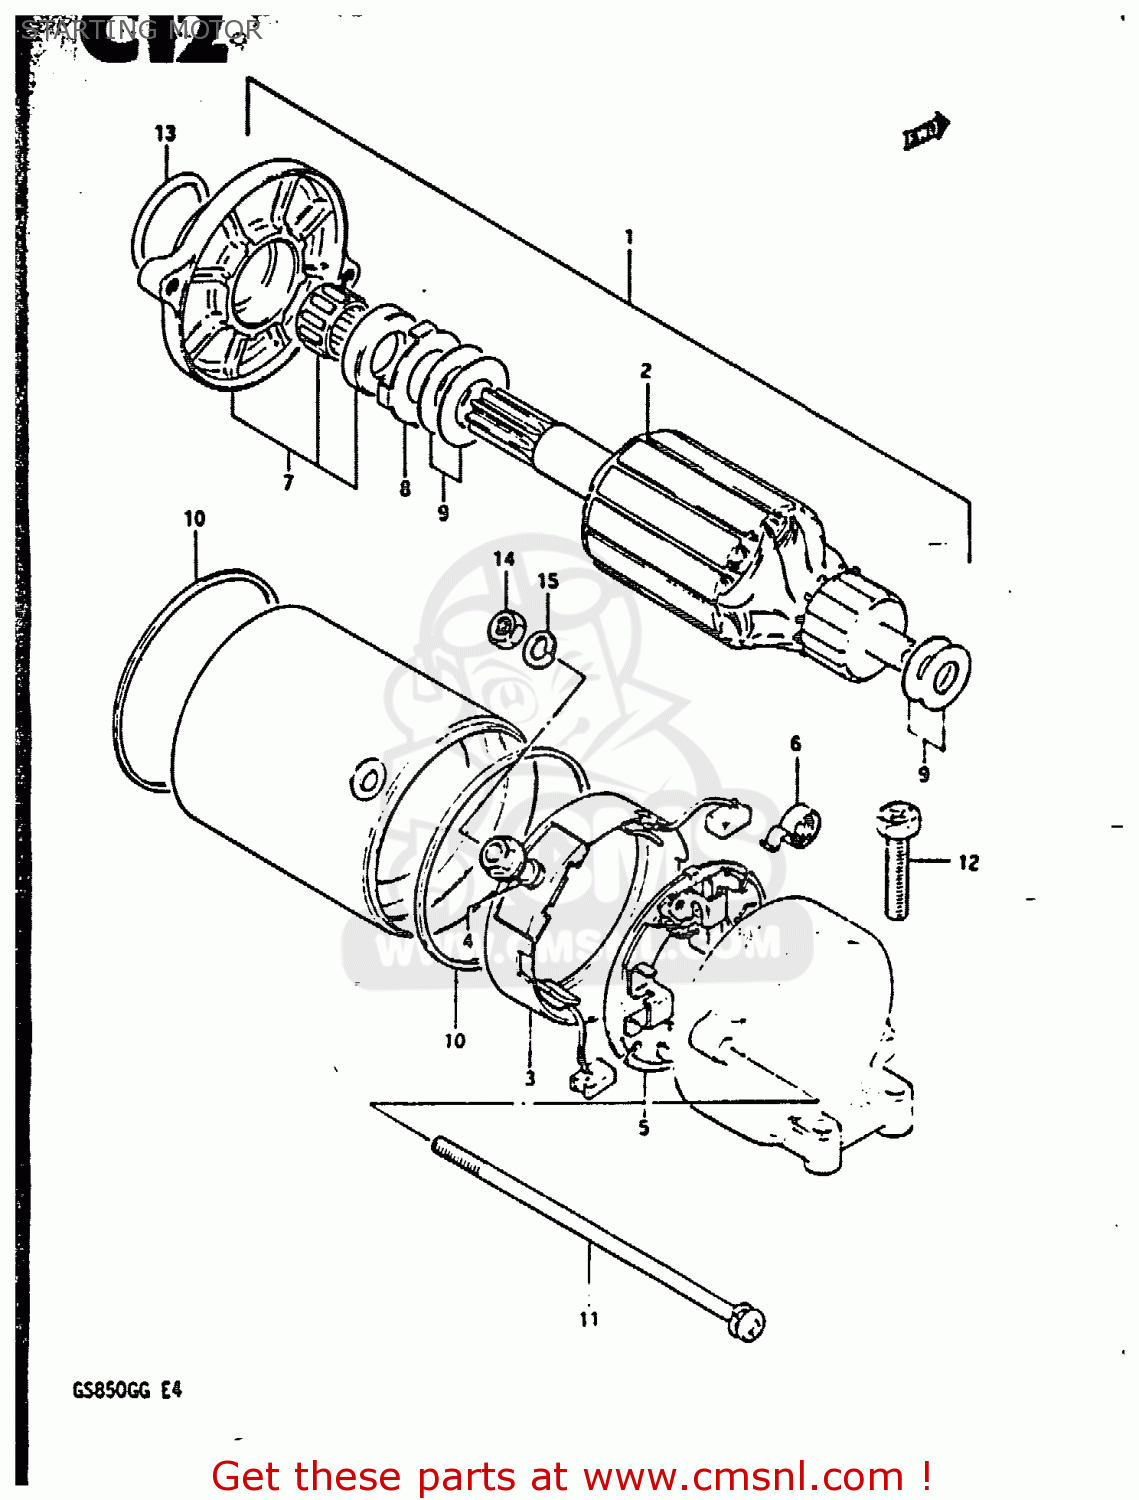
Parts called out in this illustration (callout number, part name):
1	MOTOR ASSEMBLY,STARTING
2	ARMATURE
3	BRUSH TERMINAL SET (+)
4	O RING
5	HOLDER,BRUSH
6	SPRING,BRUSH
7	HOUSING SET,STARTING MOTOR
8	SHIM SET
9	SHIM SET
10	SEAL,RING
11	BOLT,STARTING MOTOR HOUSING
12	SCREW (6X25)
13	O RING(D:3,ID:24.5)
14	NUT
15	WASHER,LOCK
